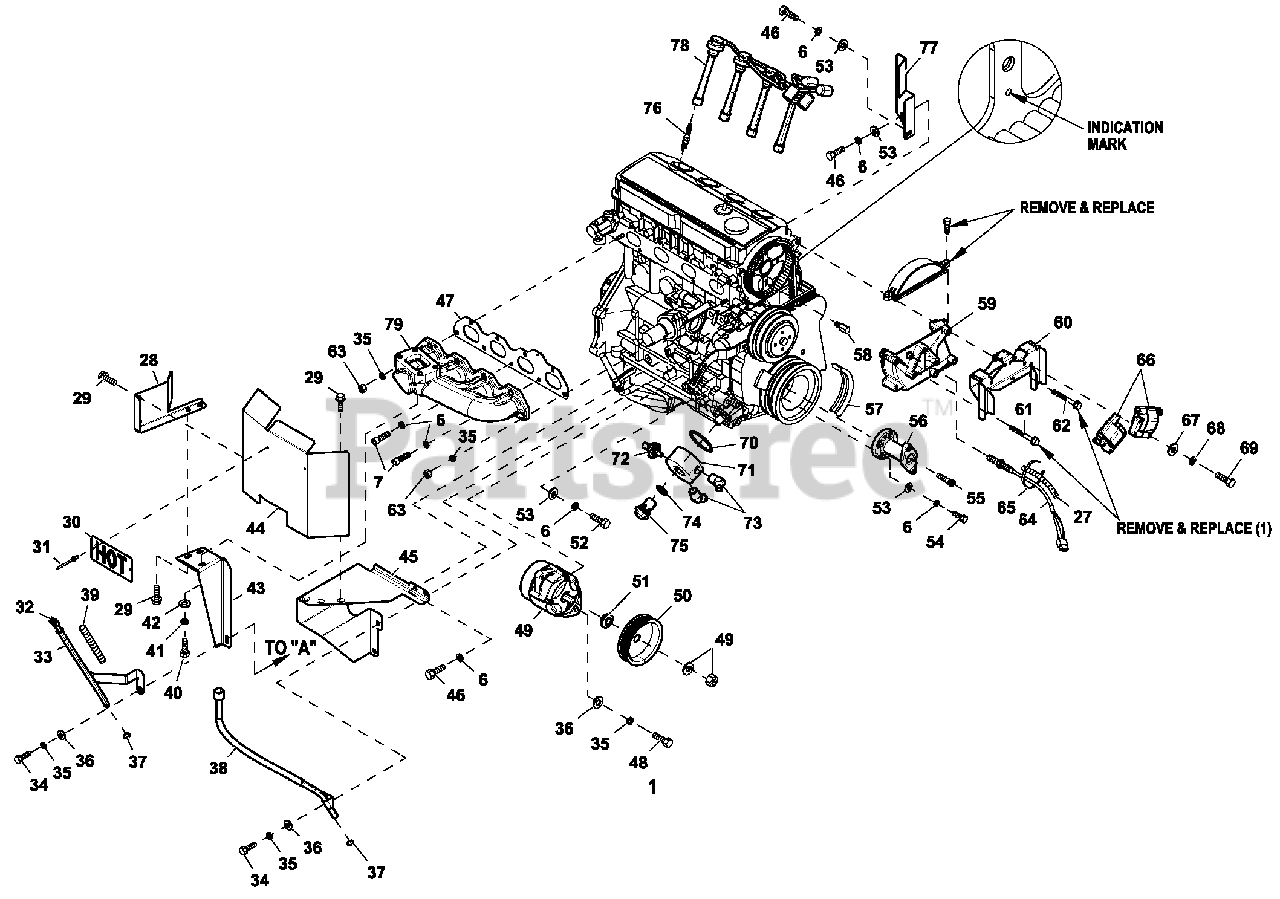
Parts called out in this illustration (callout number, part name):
1	ENGINE 2 .4 L G 2 CERTIFIED
6	W A SH ER LOCK M8-5/16
7	SCREW SHC M8-1.25 X 25
28	SHIELD INNER HEAT 2.4L TURBO
29	SCREW HHTT M6-1.0 X 12 ZINC
30	PLATE "HOT"
31	RIVET POP .1 2 5 X 0 .3 3 7 STEEL
32	ASSY DIPSTICK W /TEXT GTH-530
33	ASSY DIPSTICK TUBE 2.4 G2
34	SCREW HHC M 1 0 -1.2 5X 20 C8.8
35	W A SH ER LOCK M10
36	W A SH ER FLAT 3/8-M10 ZINC
37	O-RING SIZE 9.0MM X 2.0MM NITR
38	TUBE TURBO O IL RETURN G2 2.4L
43	BRACKET EXH MANIFOLD 2.4 TURBO
44	HEAT SHIELD TURBO 2.4L
45	BRACKET HEAT SHIELD 2.4L
46	SCREW HHC M 8-1.25X 16 C8.8
47	G ASKET EXHAUST MANIFOLD
48	SCREW HHC M 1 0 -1 .5 X 6 0 G8.8
49	ALTERN ATO R DC W /O U T PULLEY
50	PULLEY DC A LTERN ATO R (3600 RPM)
51	SPACER DC A LTERN ATO R PULLEY
53	W A SH ER FLAT 5/16-M8 ZINC
54	SCREW HHC M 8 -1 .2 5 X 3 5 G8.8
57	POLY V-BELT G2 (3600 RPM)
58	CAM SEN SOR PIN ASSY
59	CO VER CAM GEA R G2 REWORKED
60	BRACKET ASM -2.4L COIL G2
61	SCREW HHC M 8 -1 .2 5 X 6 5 C8.8
62	SCREW HHC M 8 -1 .2 5 X 7 0 G8.8
63	NUT HEX M10-1.25 G 8 Y E L C H R
67	W A SH ER FLAT #10 ZINC
68	W A SH ER LOCK #10
69	SCREW HHM #10-32 X 1-1/4
70	O-RING 2.5"X 2.75"X 1/8" VITON
71	A DA PTO R OIL FILTER 2.4L G2
72	SWITCH OIL PRESSURE 10 PSI 2 POL (R-PANEL)
74	O-RING 1 " X 1.25" X 1/8" VITON
75	NUT OIL FILTER A DA PTO R 2.4L G2
76	PLUG SPARK
77	SHIELD HEAT IGNITION COIL 2.4L
78	SPARK PLUG W IR E SET 2.4L G2 IG
79	MANIFOLD EXH 60K G2 TURBO (MA)
